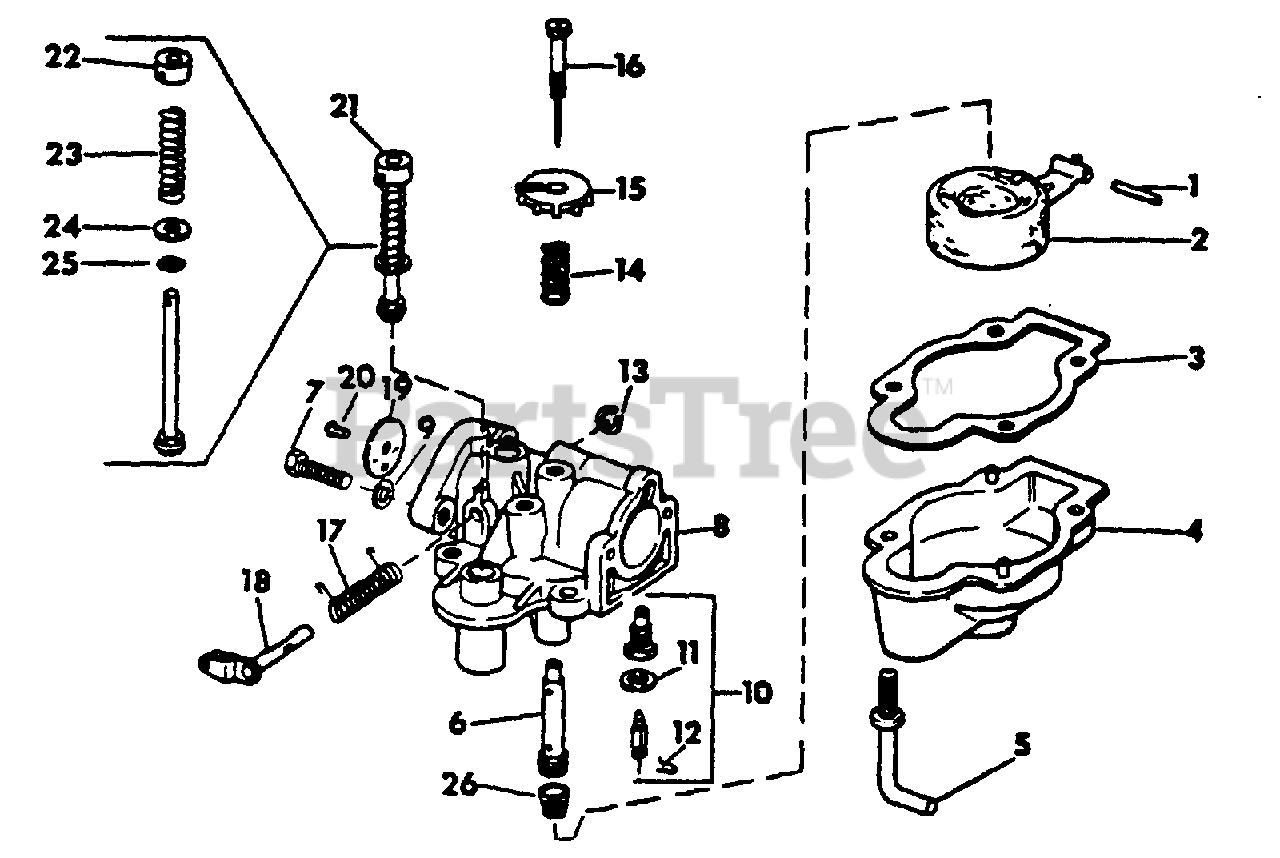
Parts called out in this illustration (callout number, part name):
1	PIN, FLOAT ARM HINGE
3	GASKET, FLOAT CHAMBER
4	CHAMBER, FLOAT
5	SCREW, FLOAT CHAMBER
8	BODY ASSY, CARBURETOR
10	FLOAT VALVE & SEAT
11	WASHER, FLOAT VALVE SEAT
14	SPRING, NEEDLE ADJ
15	KNOB, NEEDLE ADJ
17	SPRING, THROTTLE
18	THROTTLE SHAFT & LEVER ASSY
19	DISC, THROTTLE
20	SCREW, THROTTLE SHAFT DISC
21	PRIMER ASSY
22	KNOB, PRIMER
23	SPRING, COMPRESSION
